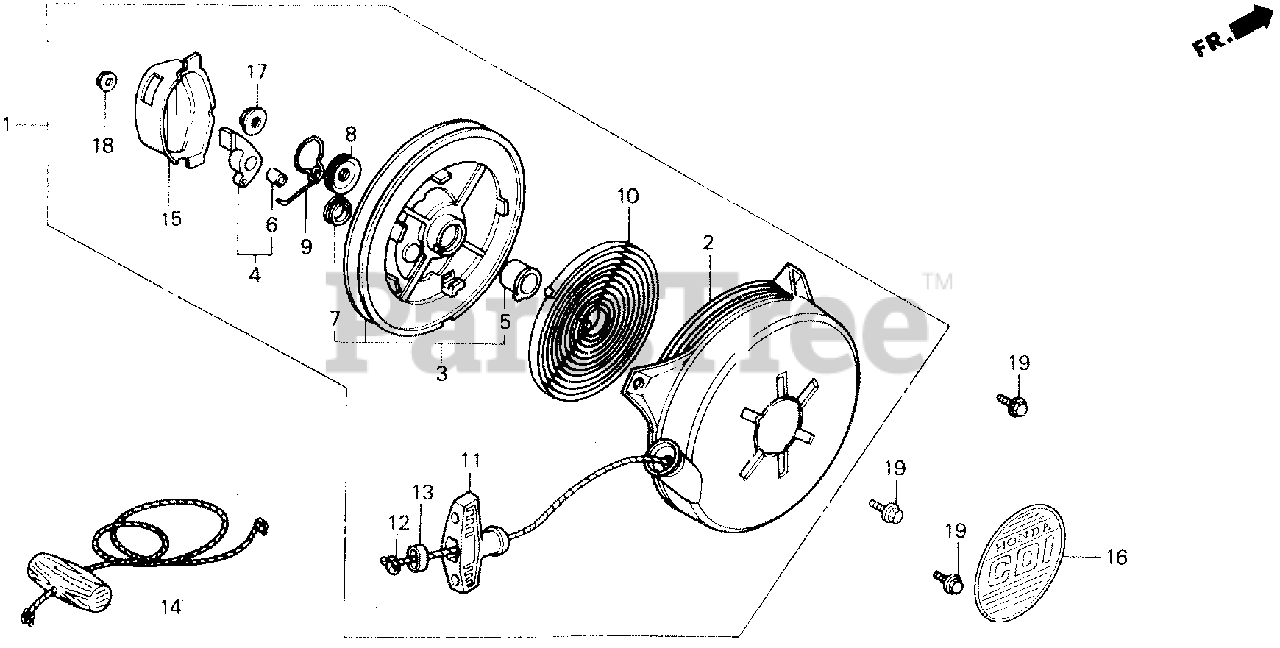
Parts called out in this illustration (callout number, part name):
1	STARTER ASSY., RECOIL *R8* (BRIGHT RED)
2	CASE, STARTER *R8* (BRIGHT RED)
3	REEL, STARTER
5	BOSS, REEL
6	BUSH, RATCHET
7	BUSH, REEL STARTER
8	PLATE, FRICTION
9	SPRING, FRICTION
10	SPRING, RETURN
11	GRIP, STARTER
12	ROPE, STARTER
13	SUPPORT, GRIP
14	ROPE, STARTER
15	COVER, STARTER REEL
16	MARK, C.D.I.
17	NUT, SELF-LOCK (8MM)
18	NUT, FLANGE (5MM)
19	BOLT, FLANGE (6X8)
